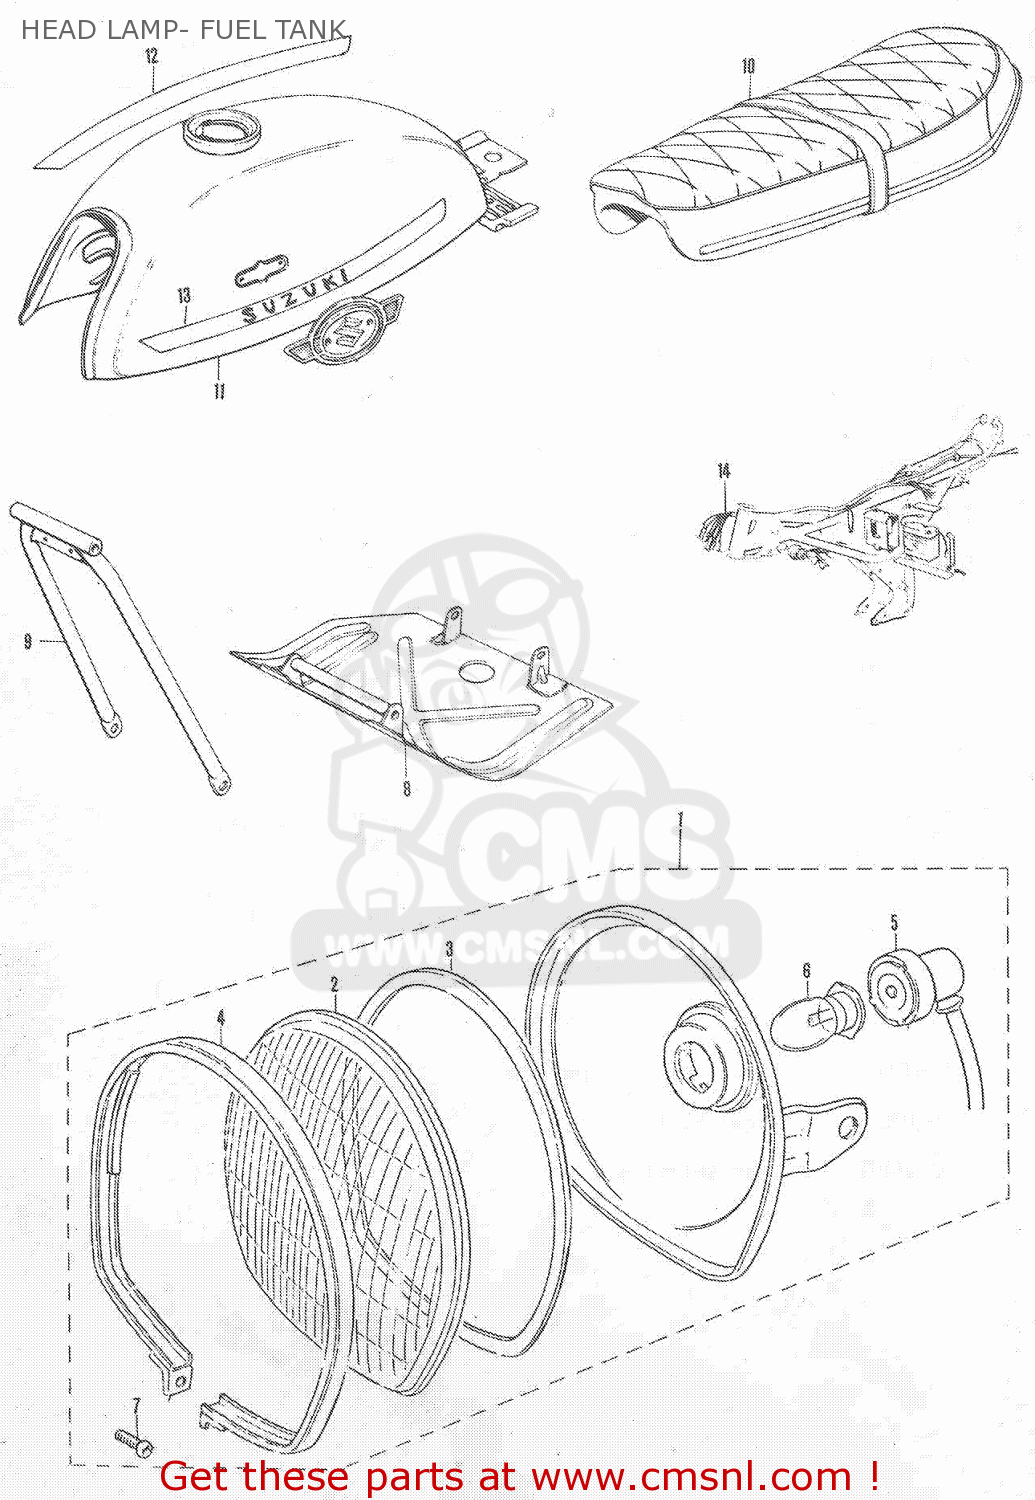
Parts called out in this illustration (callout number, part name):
1	HEAD LAMP ASS'Y
2	HEAD LAMP LENS
3	LENS GASKET
4	HEAD LAMP RIM
5	HEAD LAMP SOCKET
6	BULB
7	SCREW
8	SKID PLATE
9	SKID PLATE BRACE
10	SEAT ASSEMBLY
11	TANK ASSEMBLY,FUEL
12	TAPE,FUEL TANK
13	FUEL TANK LH STRIPE TAPE
14	HARNESS,WIRING
